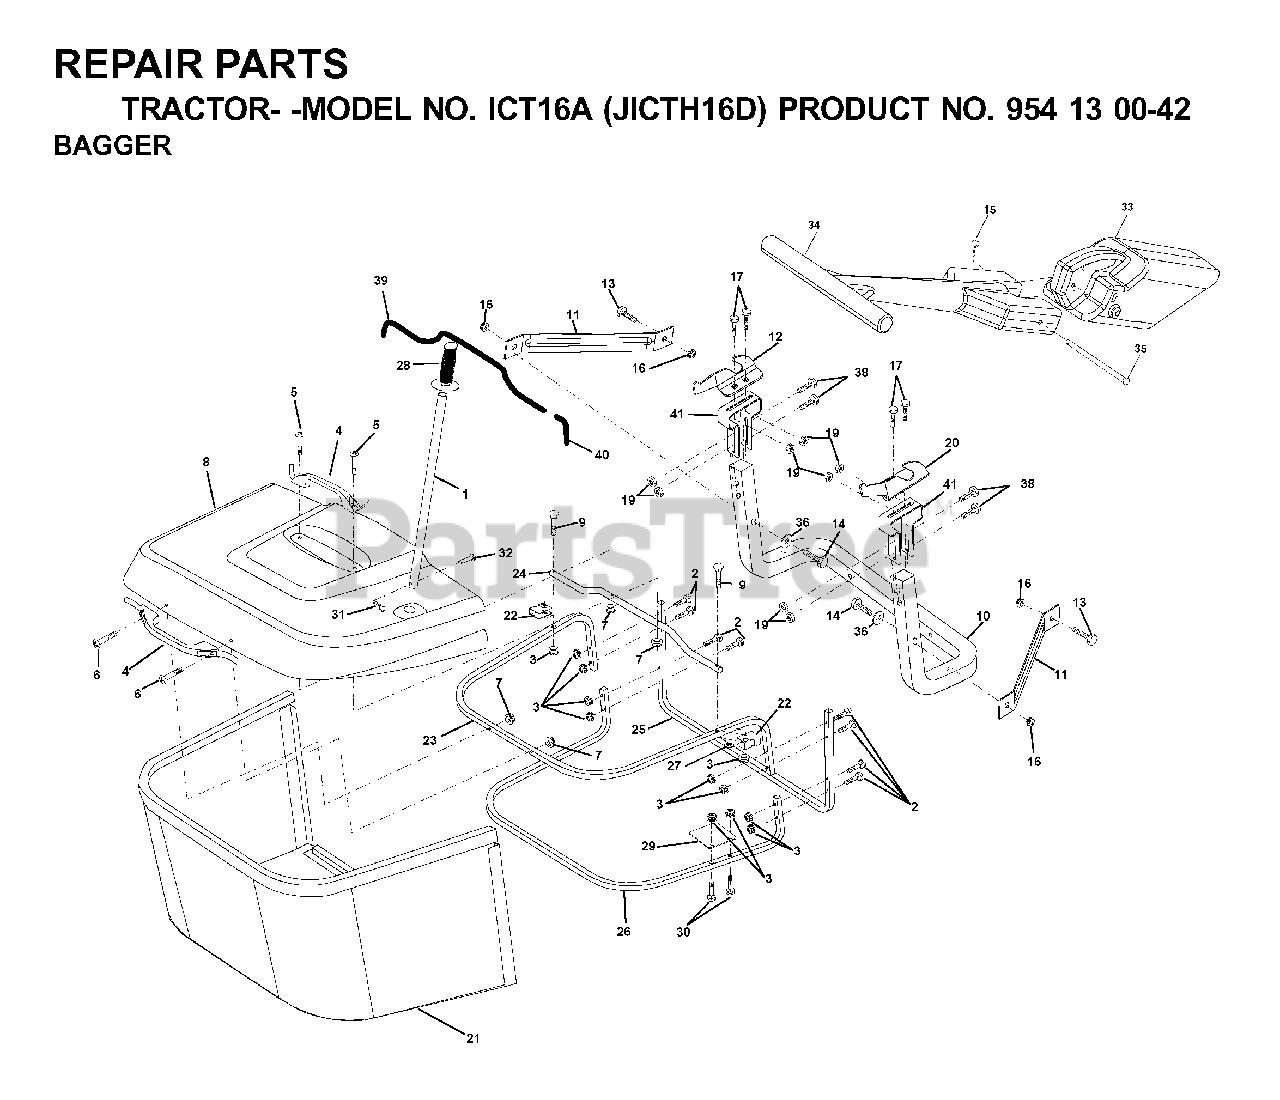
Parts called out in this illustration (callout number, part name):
1	TUBE HANDLE
3	NUT T
5	SCREW.PAN.HEAD
10	TUBE
11	BRACKET
15	RETAINER-SPRNG RB
16	NUT LOCK FLG 3/8-16 UNC
17	BOLT
19	NUT LOCK HEX FLANGE 5/16-18
20	BRACKET
21	BAG
22	BRACKET
23	TUBE
24	TUBE
26	TUBE
28	GRIP.HANDLE.BLACK
31	RETAINER M
32	RIVET,DRILLED
33	MULCH PLUG, CTH150
35	PIN
36	WASHER
38	BOLT.5/16-18X2.5
39	TRIM
40	TRIM
41	BRKT, BAGGER
